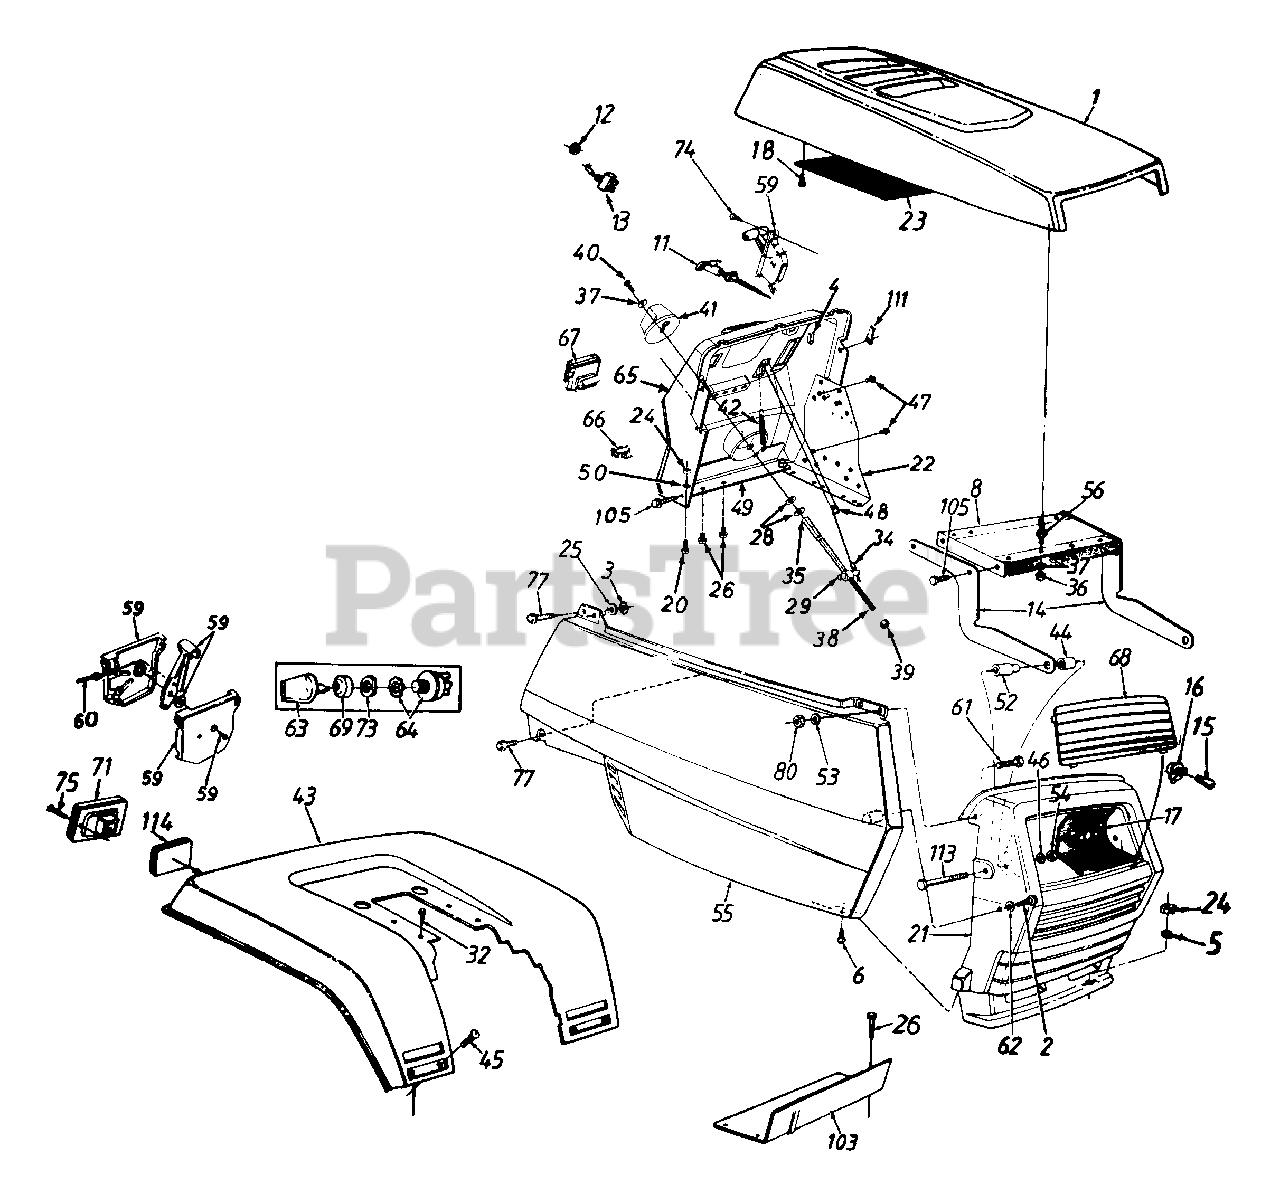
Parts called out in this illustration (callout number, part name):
1	Hood
2	Hex Wash. B-Tap Scr. 1/4 x .62" Lg.
3	Bolt Retainer 1/4" I.D.
4	Retainer Clip
5	Fl-Wash. .34" I.D. x 1"
6	Truss Mach. B-Tap Scr. #10 x .5" Lg.
8	Hood Plate
11	Choke Control (134A606F190)
11	Choke Control (134T696H190)
12	Hex Nut 1/2-27 Thd.
13	Toggle Switch
16	Twist Lock - Lamp Socket
17	Reflector - Headlight
18	Hex Wash. Hd. AB-Tap Scr. #8 x .5" Lg.
20	Hex Bolt 5/16-18 x .75" Lg.
21	Grille
24	Hex Nut 5/16-18 Thd.
25	Fl-Wash. 1/4" I.D. x .93" O.D.
26	Hex Wash. Hd. B-Tap Scr. 5/16-18 x .5" Lg.
27	Hex B-Tap Scr. #10 x .38" Lg.
28	Fl-Wash. 3/8" I.D. x .875" O.D.
29	Adj. Ferrule 3/8-8 Thd.
33	Bell-Wash. .345" I.D. x .88"
34	Hairpin Clip
35	E - Ring .375" Dia.
36	Hex Nut 1/4-20 Thd.
37	Bell-Wash. .265" I.D. x .75"
38	Adjustment Rod
39	Hex Nut 3/8-8 Twin Thd.
40	Hex Bolt 1/4-20 x .75" Lg.
41	Plastic Knob
42	Ext. Spring 3.21" Lg.
45	Carriage Bolt 1/4-20 x .50" Lg.
46	Fl-Wash. .328" I.D. x .68" O.D.
47	Hex Wash. Hd. Scr. 1/4-20 x .5" Lg.
48	Indicator Strip
49	Indicator Bracket
50	L-Wash. 5/16" I.D.
52	Shld. Spacer .33" I.D.
53	Fl-Wash. .281" I.D. x .5" O.D.
54	Hex Cent. L-Nut 5/16-18 Thd.
55	Side Cover - R.H.
55	Side Cover - L.H.
56	Double Ended Stud 1/4-20 Thd.
59	Throttle Control Box Ass'y.
60	Throttle Control Wire 22" Lg. (134A606F190)
60	Throttle Control Wire 35" Lg. (134T696H190)
61	Hex Bolt 1/4-20 x .62" Lg.
62	Fl-Wash. .281" I.D. x .73" O.D.
63	Ignition Key
64	Ignition Switch
65	Dash Panel
66	Light Switch
67	Ammeter
69	Ignition Switch Cap
71	Taillight
73	Ignition Switch Nut
74	Truss Mach. AB-Tap Scr. #10 x .5" Lg.
75	Truss Hd. AB-Tap Scr. #6 x .62" Lg.
77	Hex Wash. Hd. Tap Scr. 1/4 x .75" Lg.
80	Hex L-Nut 1/4-20 Thd.
94	Speed Nut #10-24 Thd.
111	Speed Nut 1/4-20 Thd.
113	Hex Bolt 5/16-18 x 2.75"
114	Reflector (134A606F190)
17324B-0648	Fender - TECH GRAY (0648)
